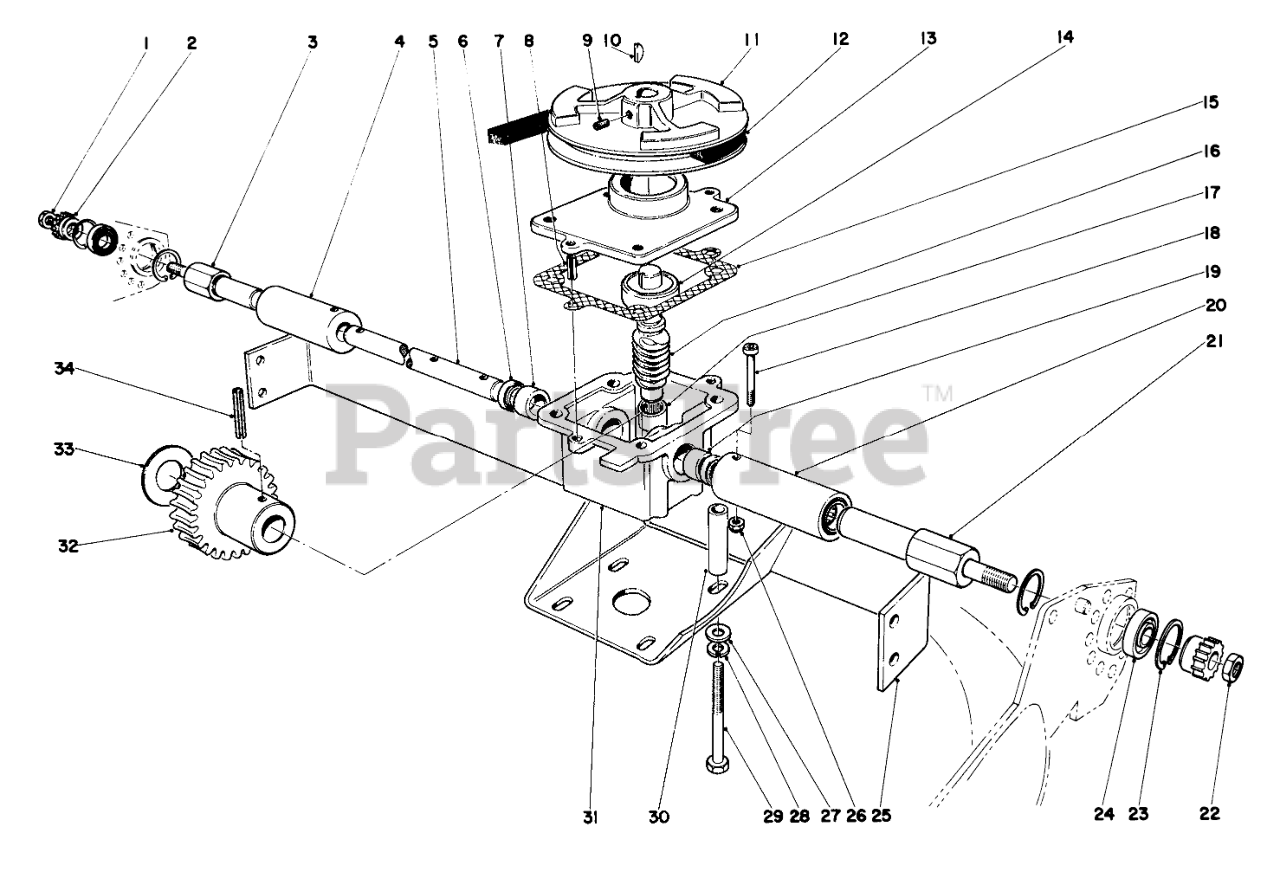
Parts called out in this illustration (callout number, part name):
1	NUT-HJ
2	Pinion Kit
3	OUTPUT SHAFT
4	R/H CLUTCH HSG ASM
5	GEAR BOX SHAFT
6	Seal
7	Bushing
8	3/16 X 1/2 ROLL PIN
9	SCREW-HSH
10	3/32X5/8 WOODRUFF KEY
11	GEAR BOX PULLEY
12	V-BELT
13	Cover Gear Box
14	Bearing
15	GASKET
16	WORM SHAFT
17	.437 NEEDLE BEARING
18	DRIVE SCREW
19	Bushing
20	L/H CLUTCH HSG ASM
21	OUTPUT SHAFT
22	Nut
23	1-1/8X056 IN SNP RING
24	.375 RPP BALL BEARING
25	Support, Gear Case
26	NUT-LOCK, NI
27	WASHER-FLAT
28	WASHER-LOCK
29	SCREW-HH
30	GEAR CASE SPACER
31	Gear Case (Incl. Ref. Nos. 7, 17 & 19)
32	WORM GEAR
33	THRUST WASHER
34	5/32 X 7/8 ROLL PIN
